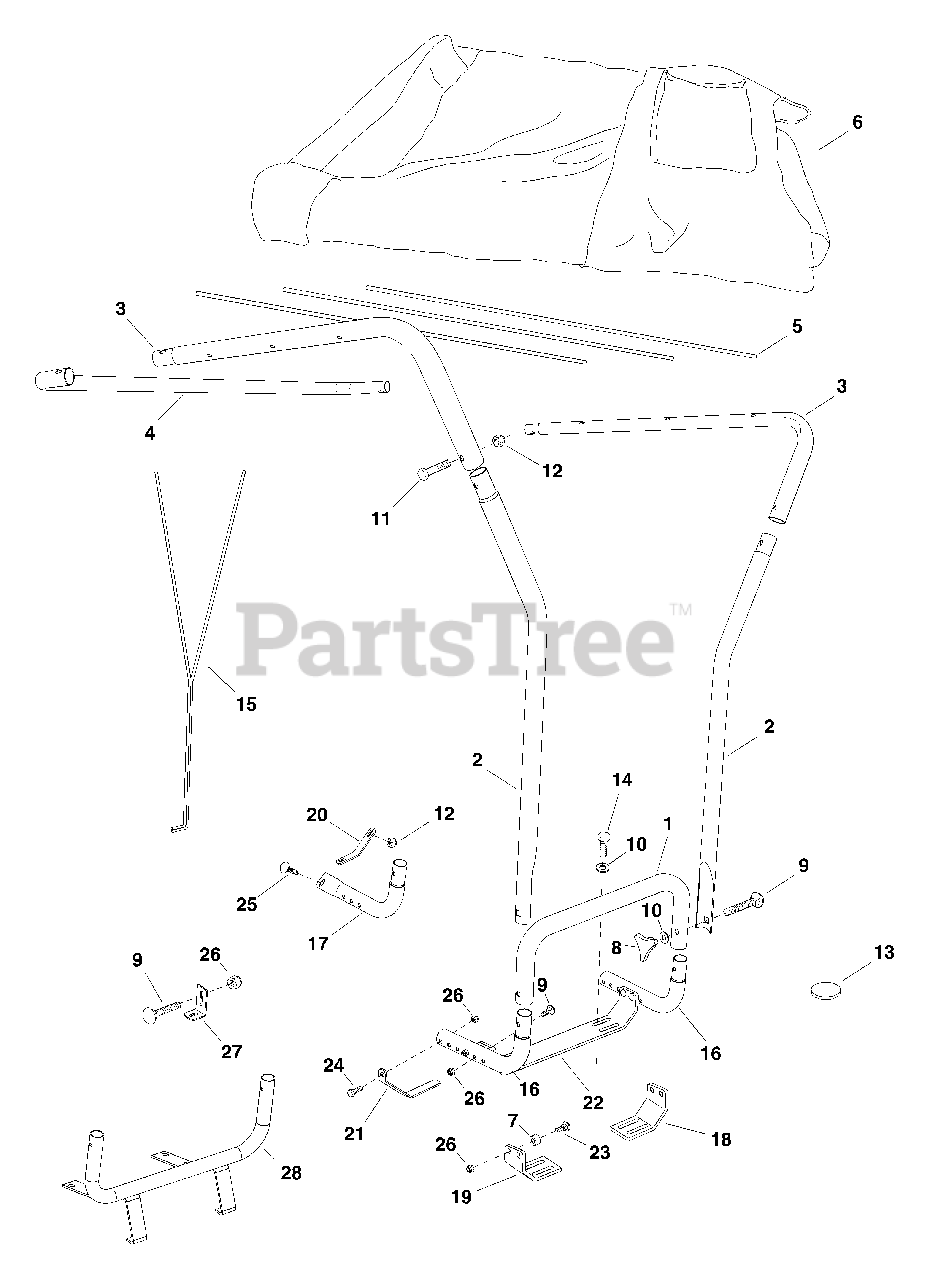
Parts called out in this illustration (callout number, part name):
1	Upper Base Tube
2	Upright Tube
3	Top Tube
5	Support Rod
6	Vinyl Canopy
8	Plastic Knob
9	Carriage Bolt, 5/16-18 x 2"
10	Flat Washer, 5/16"
11	Hex Bolt, 1/4-20 x 1-1/2"
12	Nylock Nut, 1/4-20
13	Adhesive Pad
14	Hex Bolt, 5/16-18 x 1"
15	Front Brace Rod
16	Base Leg Tube
17	Base Leg Tube, Flattened
18	Right Base Bracket
19	Left Base Bracket
20	Right Support Bracket
21	Left Support Bracket
22	Base Bracket
23	Carriage Bolt, 5/16-18 x 2-3/4"
24	Hex Bolt, 5/16-18 x 2"
25	Carriage Bolt, 1/4-20 x 1"
26	Nylock Nut, 5/16-18
27	Rear Support Bracket
28	Base Bracket Assembly
